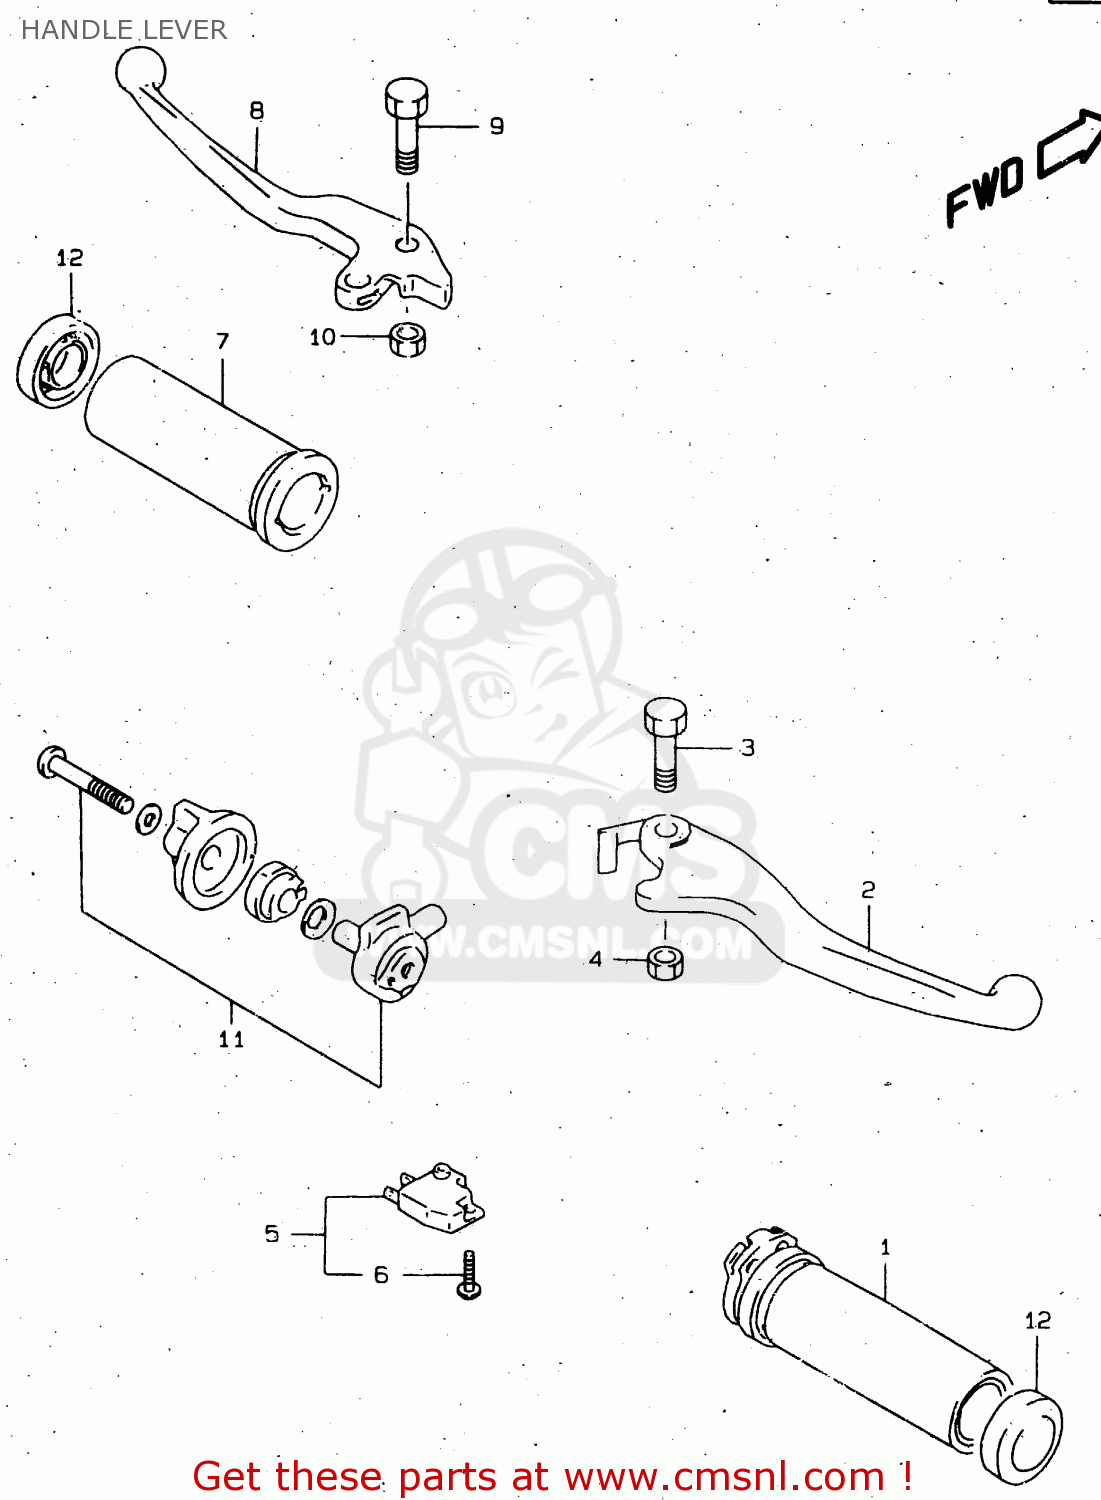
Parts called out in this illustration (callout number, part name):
1	GRIP,THROTTLE
2	LEVER,BRAKE
3	BOLT,LEVER SET
4	NUT 6MM
5	SWITCH ASSEMBLY,STOP
6	SCREW
7	GRIP,L
8	LEVER,CLUTCH
9	BOLT,LEVER SET
10	NUT 6MM
11	LEVER ASSY,STARTER
12	CAP,GRIP END
